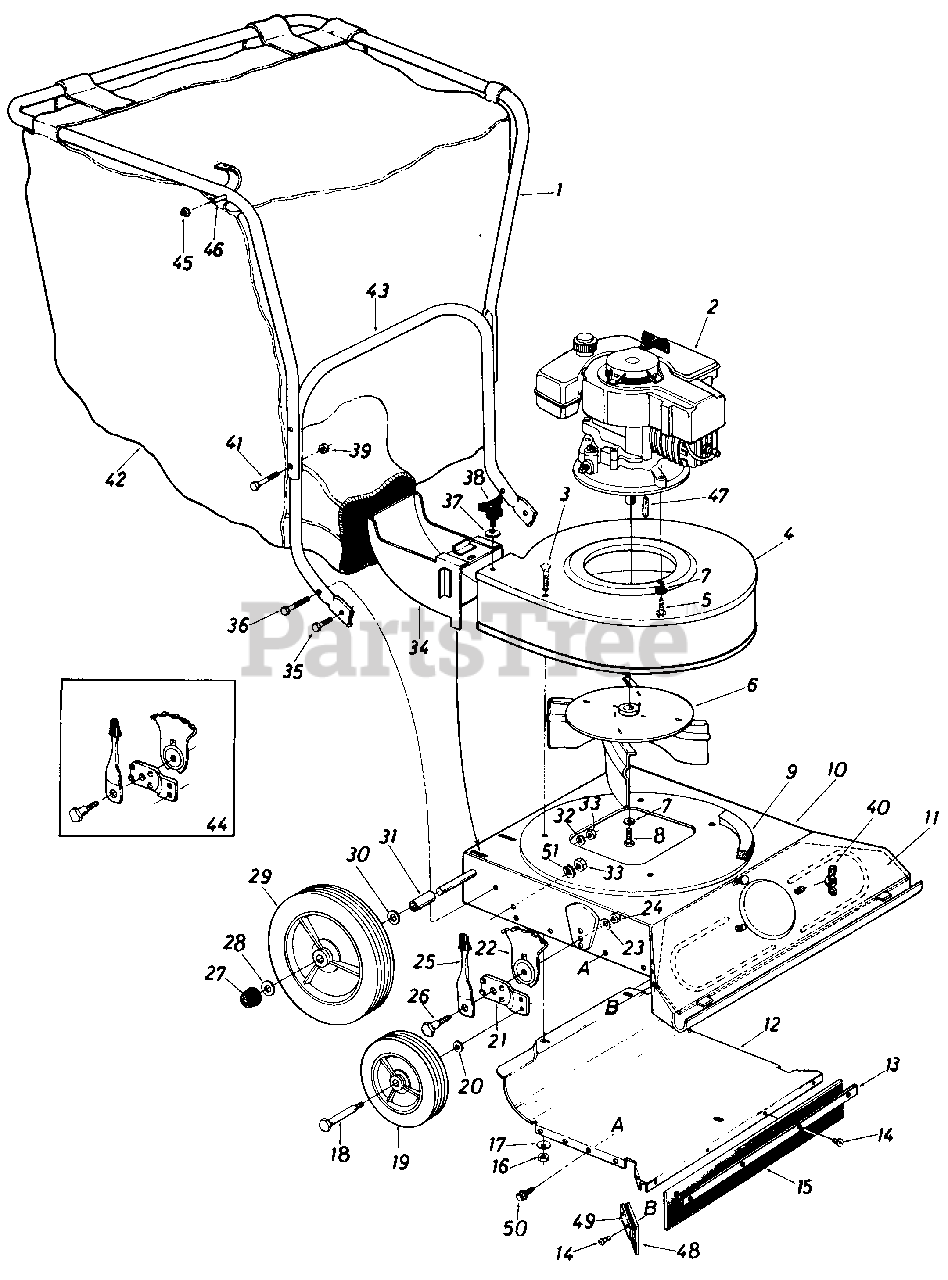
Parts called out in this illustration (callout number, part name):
1	Upper Handle
2	Engine
3	Carriage Bolt 5/16-18 x .62" 4.*
4	Blower Housing Ass'y.
5	Hex Tap Scr. 3/8-16 x l.00" Lg.
6	Impeller Ass'y.
7	L.-Wash 3/8" I.D.*
8	Hex Bolt 3/8-24 x 1.0" Lg. w/ Patch
9	P.V.C. Foam Strip (4-Pcs. 12" Lg.)
10	Vacuum Deck Ass'y.
11	Front Baffle Ass'y.
12	Lower Baffle Ass'y
13	Wiper Retaining Strip
14	Pop Rivet .188" Dia.
15	Nozzle Wiper Rear
16	Hex Nut 5/16-18 Thd.*
17	Bell.-Wash. .34" I.D. x .87" O.D.
18	Shld. Bolt 1/2" Dia. x 1.45" Lg. (3/8-18)
19	Wheel Ass'y. Comp. 8 x 1.75" - Front
20	Bell. Wash. .39" I.D. x 1.12" O.D.
22	Index Plate
23	Bell.-Wash. .39" I.D. x 1.12" O.D.
24	Hex Nut 3/8-16 Thd.*
25	Spring Lever Ass'y. w/ Knob
26	Shoulder Bolt .500" x 7/16" Lg. (3/8-16)
27	Push Cap 50" Rod (Black)
28	Fl.-Wash. 1/2" I.D. x 1.0" O.D. x .06
29	Wheel Ass'y. Comp. 10 x 1.75" - Rear
30	Fl.-Wash. 1/2" I.D. x 1.0" O.D. x .06
31	Wheel Spacer 1/2" I.D. x 15/16" Lg.
32	Bell.-Wash. .39" I.D. x 1.12" O.D.
33	Hex Nut 3/8-16 Thd.*
34	Air Duct Ass'y.
35	Hex Bolt 3/8-16 x .75" Lg.*
36	Hex Bolt 3/8-16 x 1.50" Lg.*
37	Bell.-Wash. .34" I.D. x .87" O.D.
38	Thumb Scr. 5/16-18 x .75" Lg.
39	Hex Cent. L.-Nut 1/4-20 Thd.
40	Wing Nut 1/4-20 Plastic)
41	Hex Bolt 1/4-20 x 1.75" Lg.*
42	Vacuum Bag (6.6 Bushel)
43	Lower Handle
44	Height Adjuster Ass'y. Comp.-R.H.
45	Push Speed Nut .25" Dia.
46	Stud Pin .250" Dia. x 1.75 Lg.
47	Sq. Key 3/16 x 3/16 x 1.00" Lg.
48	Nozzle Wiper Side
49	Wiper Retaining Strip
50	Hex Wash. Hd. "F" Tap Scr. #10
51	L-Wash. 3/8" I.D.*
